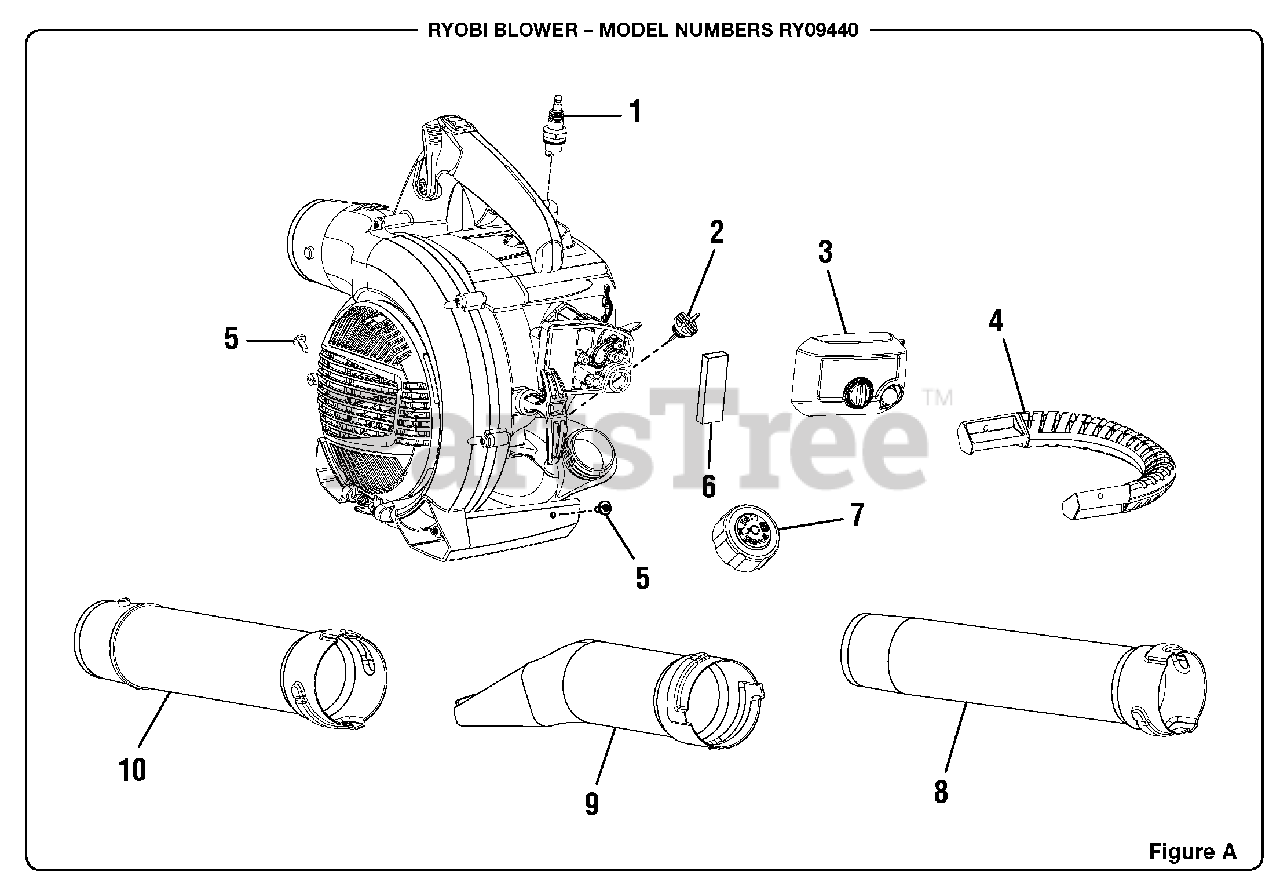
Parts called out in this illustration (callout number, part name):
1	Spark Plug (RCJ6Y)
2	Oil Fill Cap w/Dipstick
3	Air Filter Cover
5	Screw (10-14 x 1/2 in.)
7	Fuel Cap Assembly
8	Sweeper Nozzle
9	High Velocity Nozzle w/Leaf Scraper
10	Upper Blower Tube
